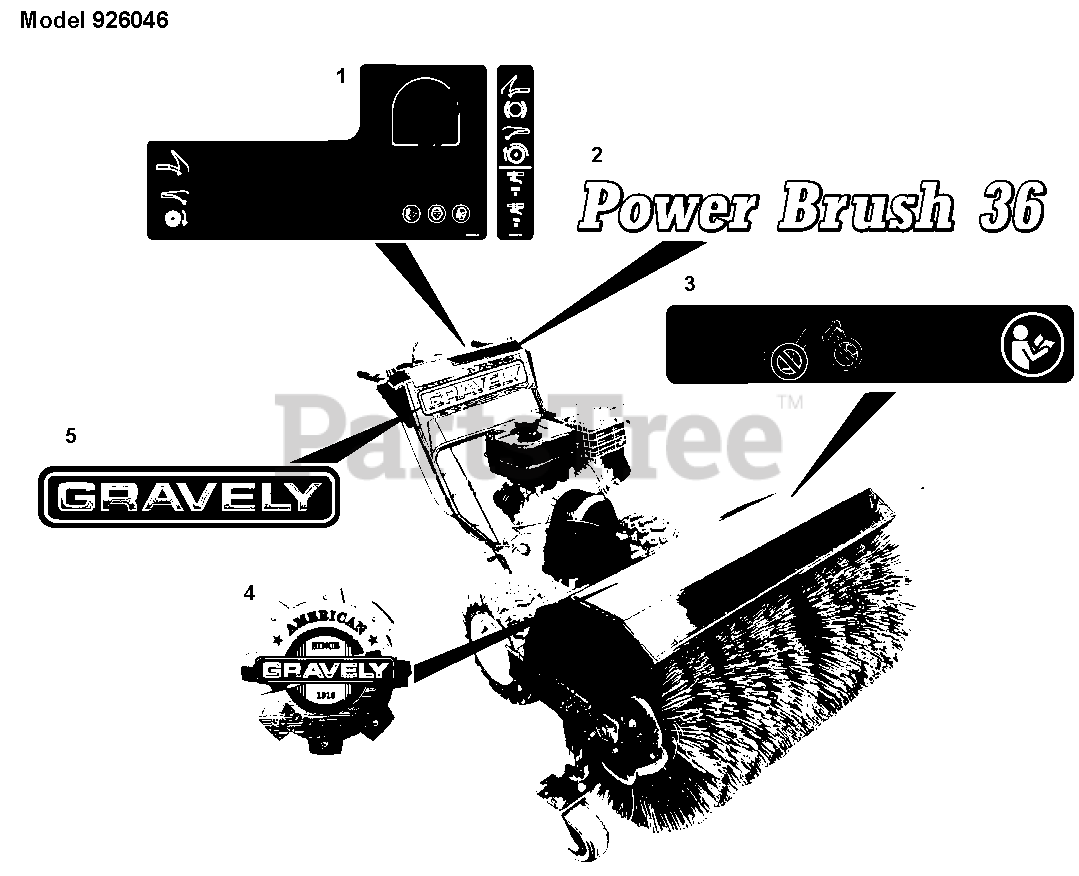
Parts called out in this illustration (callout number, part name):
2	Decal, Power Brush 36"
3	Decal, Danger
4	Decal, Gravely Heritage
5	Decal, 13.50" Gravely Logo
